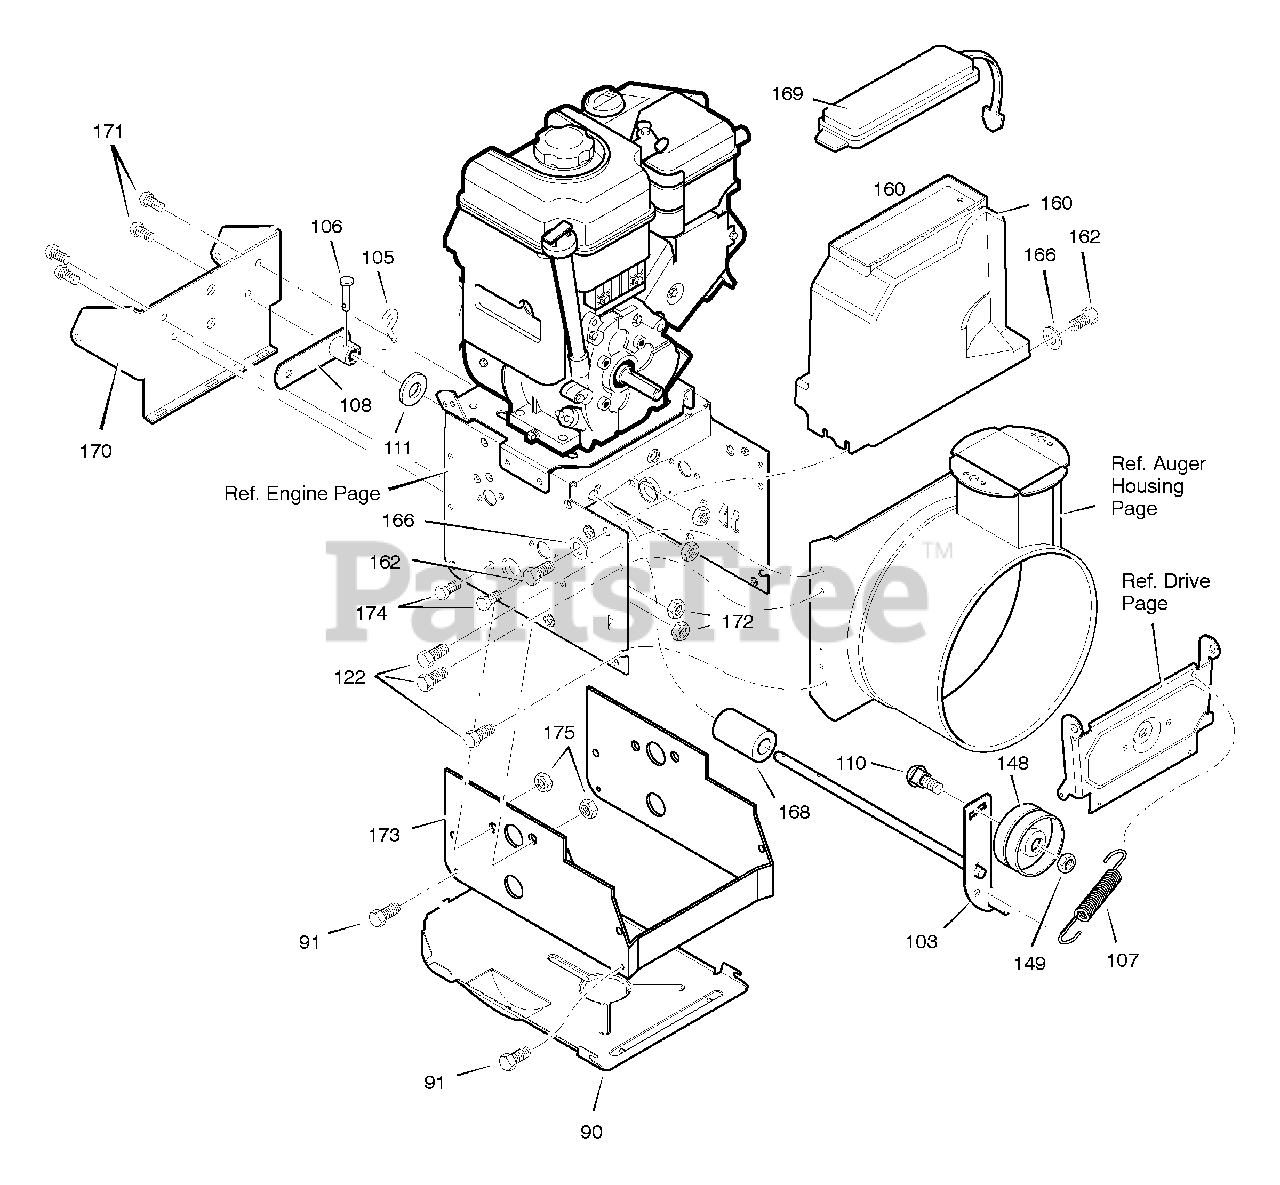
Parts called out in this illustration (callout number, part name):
90	COVER, BOTTOM
91	SCREW, 1/4-20X .62
103	IDLER ASSEMBLY, AUGER
105	PIN, HAIR .38DIAX1.64LG
106	PIN, CLEVIS 3/16" DIA
107	SPRING, TENSION
108	ASSY., SPRING ATTACH
110	BOLT, 3/8-16X1.25 CARR.
111	WASHER, FLAT
122	SCREW, TAP 5/16-18 X .50
148	PULLEY, IDLER
149	NUT, JAM 3/8-16
160	COVER, BELT
162	SCREW, TAP 1/4-20 X .63
166	WASHER, FLAT
168	SPACER, AUGER BRACKET
169	LID, TOOL BOX
170	BRACKET, TRACK SUPPORT
171	SCREW, 5/16-18 x 0.75
172	NUT, 5/16-18
173	EXTENSION, FRAME
174	SCREW, 3/8-16 X 0.75
175	NUT, 3/8-16
